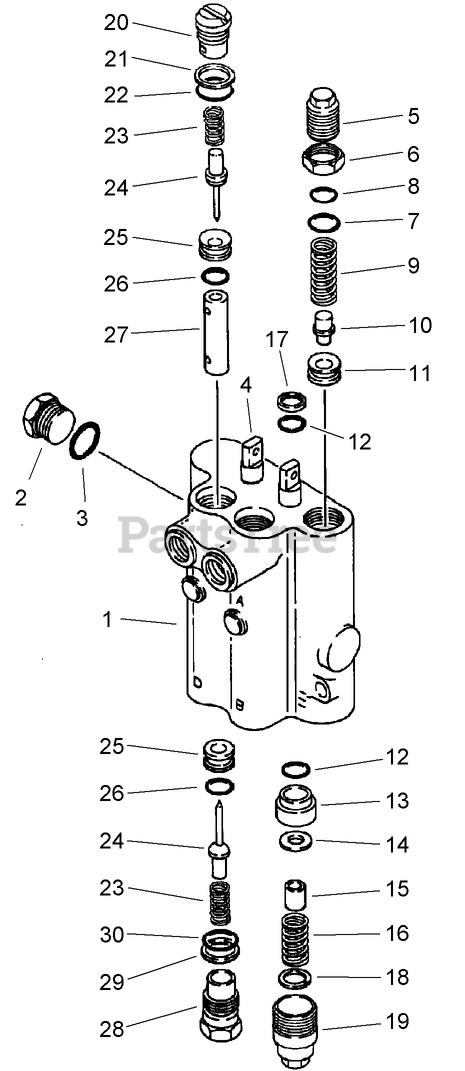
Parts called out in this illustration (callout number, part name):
1	BODY - Valve
2	PLUG - Special, Valve Body
3	O-RING
4	SPOOL - Steering Control Valve
5	PLUG - Relief Valve
6	NUT-LOCK, FTG
7	O-RING
8	SHIM - 0.3 mm (.010 inch) Thick, Relief Valve
8	SHIM - 0.4 mm (.015 inch) Thick, Relief Valve
8	SHIM - 0.9 mm (.035 inch) Thick, Relief Valve
9	SPRING - Valve
10	POPPET - Valve
11	SEAT - Relief Valve
12	O-RING - Special
13	BUSHING - Spool
14	WASHER - Flat, Special
15	SPACER - Spacer
16	SPRING - Centering
17	SEAL - Wiper, Spool
18	RING-RETAINING
19	CAP - Valve Body, Valve Body
20	PLUG - Seat Retaining
21	RING - Backup, Plug O-Ring
22	O-RING - 5/8 ID x 3/32 inch Wide
23	LOCK-SPRING
24	POPPET
25	SEAT - Poppet
26	O-RING
27	PLUNGER - Valve, Valve
28	PLUG - Lower Port
29	RING - Backup, Plug O-Ring
30	O-RING - 5/8 ID x 3/32 inch Wide
